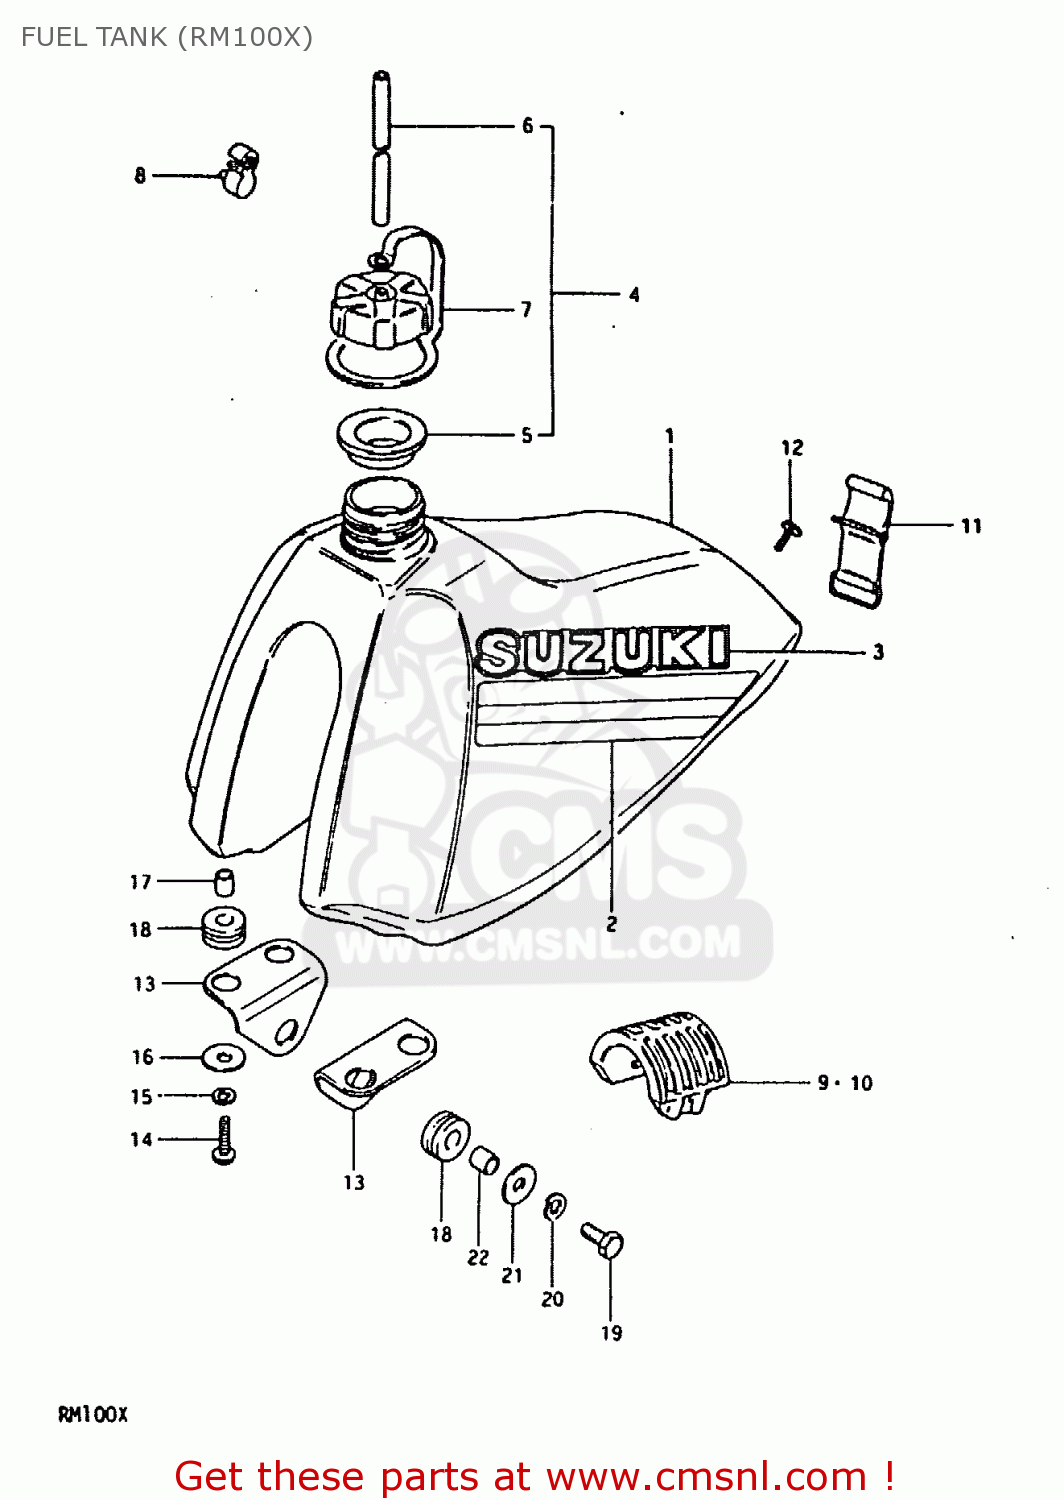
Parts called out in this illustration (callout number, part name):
1	TANK, FUEL (YELLOW)
2	TAPE SET
3	EMBLEM
4	CAP SET,FUEL TANK
5	GASKET,FUEL TANK CAP (NAS)
6	HOSE
7	BAND,FUEL TANK CAP
8	CLAMP,BREATHER HOSE
9	CUSHION,FUEL TANK
10	CUSHION,FUEL TANK
11	BAND
12	SCREW(6X18)
13	BRACKET,FUEL TANK,LOWER
14	SCREW
15	LOCK WASHER
16	WASHER (6.5X24X1.6)
17	SPACER(6.8X12X11)
18	CUSHION
19	BOLT
20	LOCK WASHER
21	WASHER (8.2X24X1.6)
22	SPACER (8.8X12X11)
